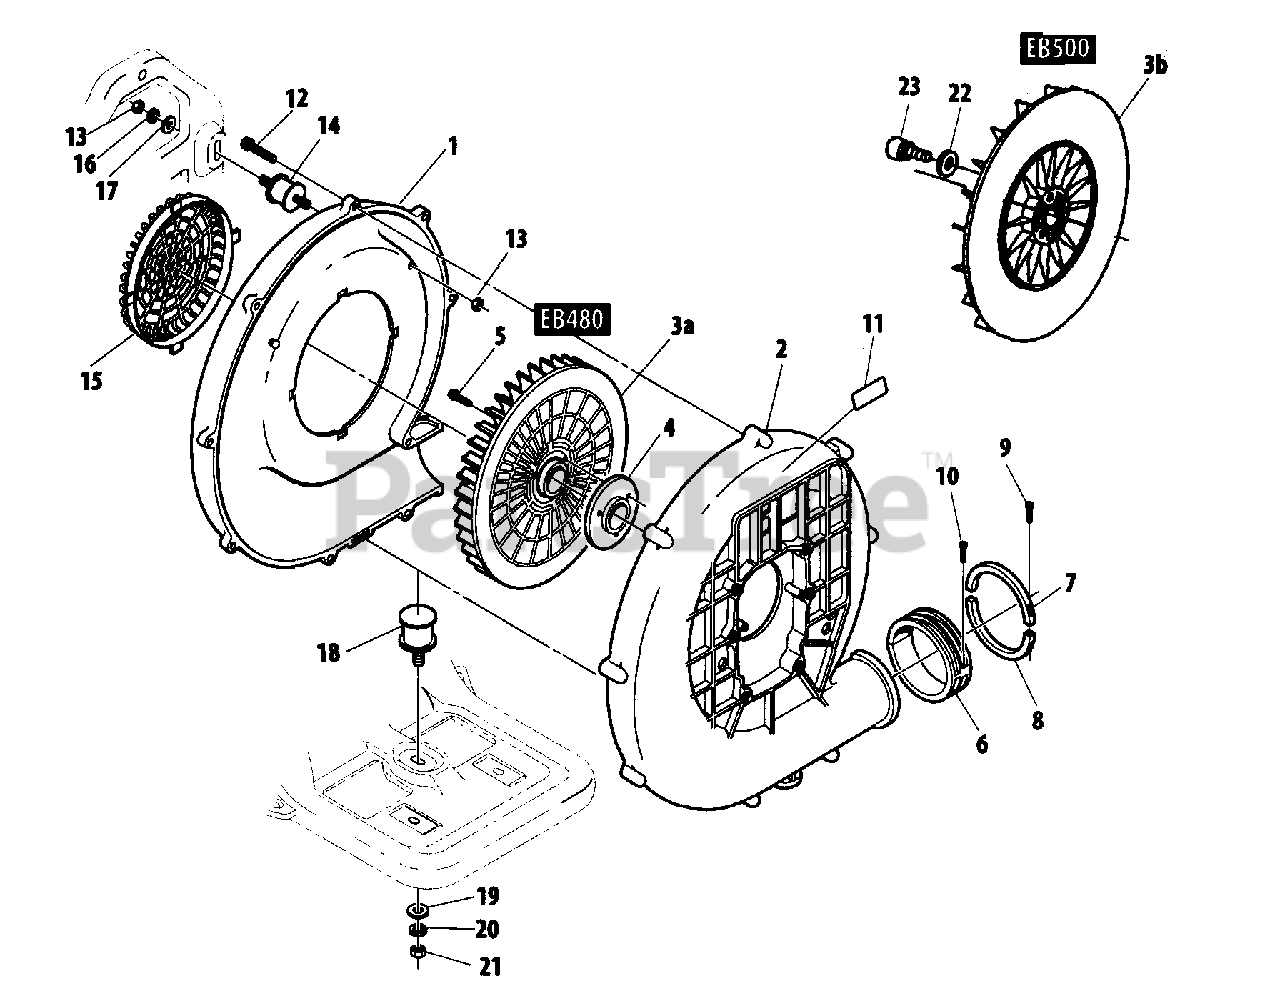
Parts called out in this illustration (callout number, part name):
1	COVER, FAN - INNER
2	COVER, FAN - OUTER
3A	IMPELLER
3B	FAN, BLOWER
5	BOLT M6×40
6	SLEEVE
7	RETAINING RING (A)
8	RETAINING RING (B)
9	SCREW
10	SCREW, TAPPING
12	BOLT, TAPPING 5
13	NUT M5
14	CUSHION 5
15	COVER, INTAKE
16	WASHER, SPRING 5
17	WASHER 5
18	CUSHION 6
19	COLLAR Ø18ר6.4×L2
20	WASHER, SPRING 6
21	NUT, HEX M6
22	WASHER 6
